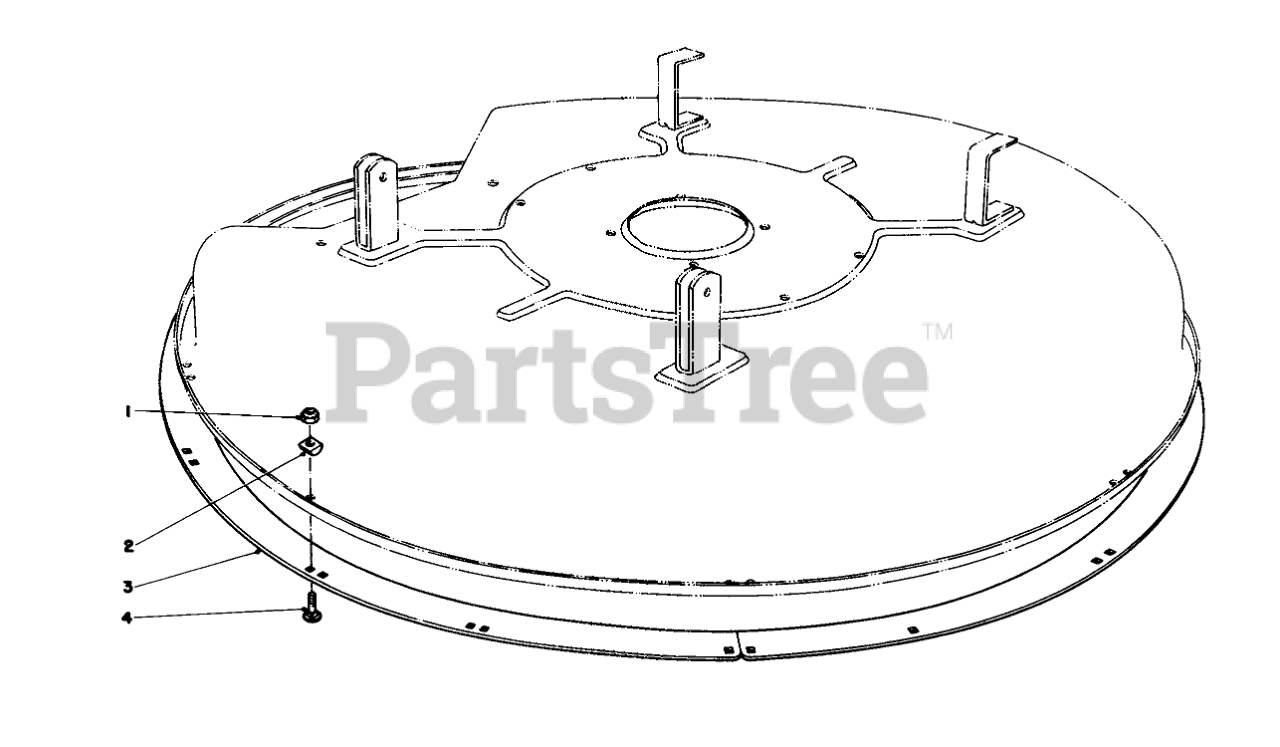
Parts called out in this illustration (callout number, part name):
1	NUT-LOCK, NI
2	DECK RING SPACER
3	DECK RING B
4	BOLT-CARR
